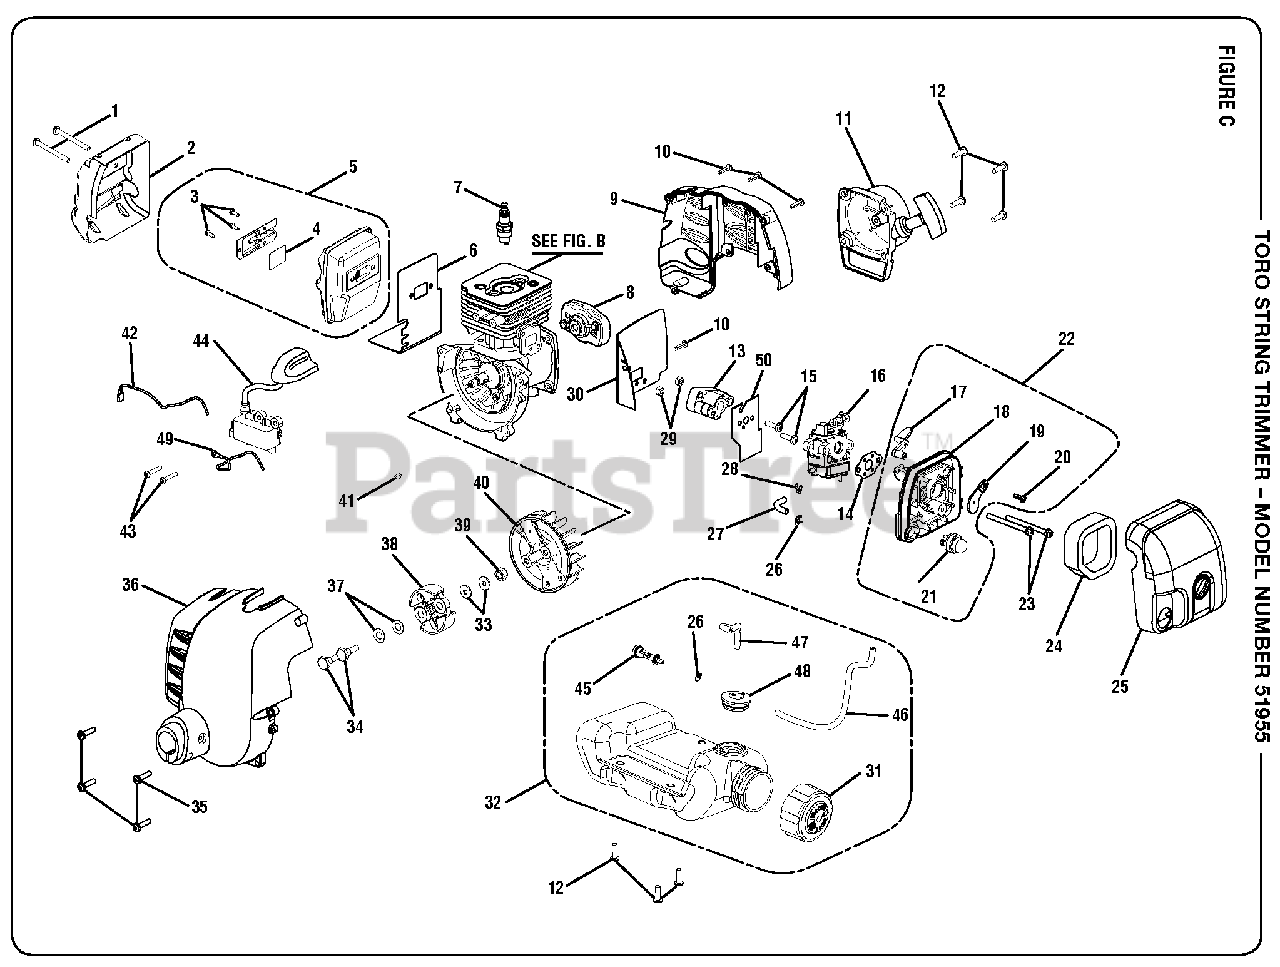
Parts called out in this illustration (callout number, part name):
1	Screw (M5 x 50 mm, Torx Slotted Recessed Pan Hd.)
2	Heat Shield
3	Screw Recess Pan Hd.)
4	Screen
5	Muffler Assembly
6	Muffler Gasket
7	Spark Plug (RCJ6Y)
8	Starter Cup
9	Engine Housing, Rear
10	Screw (M4 x 16 mm, Torx Recessed Pan Hd.)
11	Starter Recoil Assembly
12	Screw (m5 x 16 mm, Torx Slotted)
13	Heat Dam Insulator
14	Carburetor Gasket
15	Screw (M5 x 31 mm Torx Slotted Recessed Pan Hd.)
16	Carburetor Assembly
17	Choke Lever
18	Carburetor Plate
19	Choke Plate
20	Screw (M4 x 12 mm, Slotted Recessed Pan Hd.)
21	Primer Assembly
22	Filter Housing Assembly
23	Screw (M5 x 60 mm, Slotted Recessed Pan Hd. Machine)
24	Element
25	Cover Assembly
26	Hose Clip
27	Fuel Line (45 mm)
28	Hose Clip
29	Nut (M5 x .8 mm)
30	Insulator Gasket
31	Fuel Cap Assembly
32	Fuel Tank and Cap Assembly
33	Washer
34	Clutch Screw
35	Screw (M5 x 20 mm Torx Slotted Recessed Pan Hd.)
36	Front Housing Assembly
37	Curved Washer
38	Clutch Assembly
39	Rotor Nut
41	Woodruff Key (10 mm x 3 mm)
42	Lead Wire, Black
43	Screw (M4 x 22 mm, Torx Slotted Recessed Pan Hd.)
44	Coil Boot Assembly
45	Fuel Filter
46	Fuel Line (150 mm)
47	Fuel Line (118 mm)
48	Grommet
49	Lead Wire, Red
